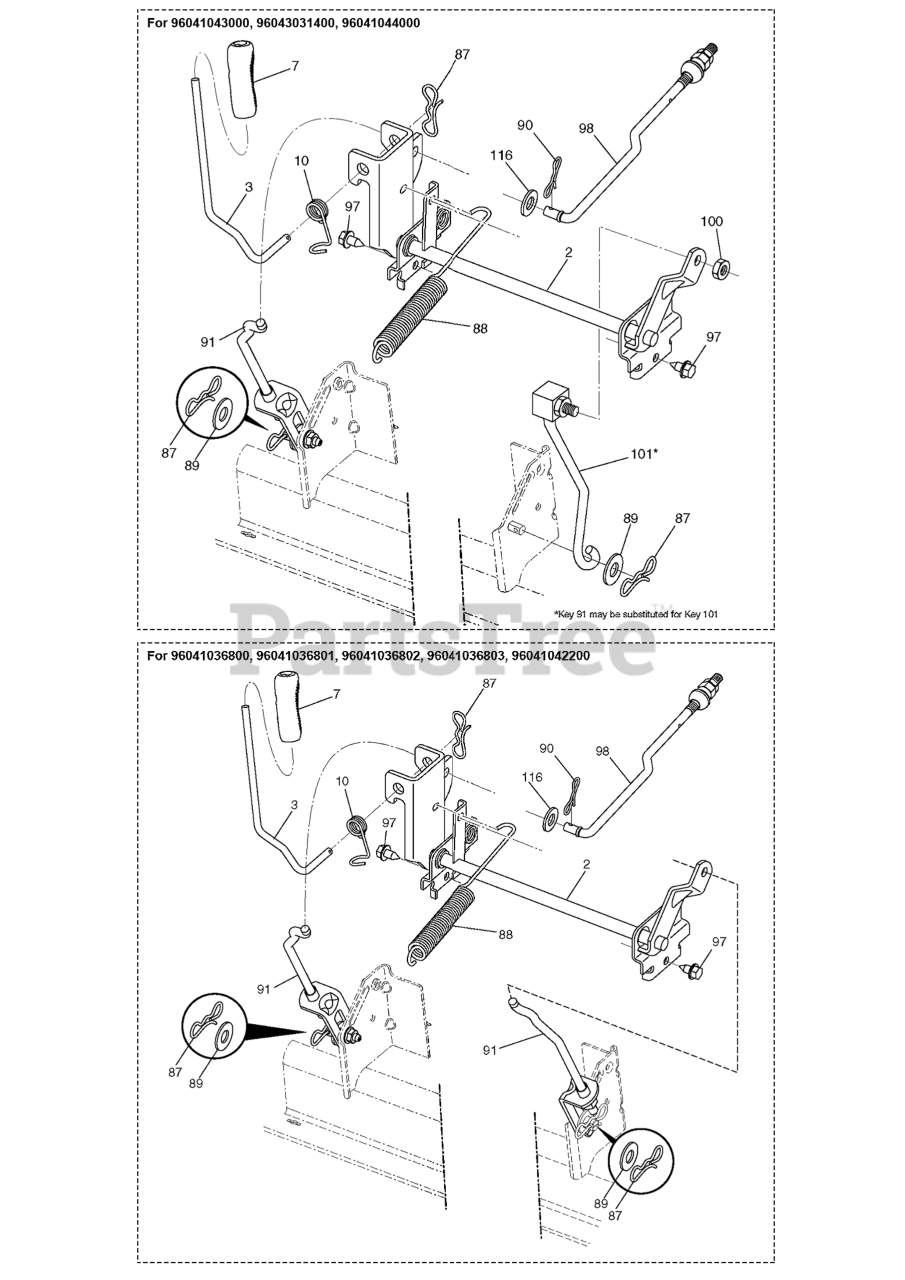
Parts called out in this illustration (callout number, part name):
2	SHAFT.ASM.CROSS.LIFT
3	Levers
3	LEVER.LIFT.HANDLE.LT
7	GRIP.HANDLE.LIFT.PVC.BLACK
10	SPRING.TORSION.LIFT.HANDLE
87	PIN.COTTER.7/16.BOW TI.
88	SPRING.LIFT.ASSIST
89	WASHER.CLEAR.ZINC
90	PIN.COTTER.5/16.BOW TI
91	LINK ASSY LIFT.REAR 10.278
91	Links
97	SCREW, 3/8-16X3/4
98	LINK.ASM.SUSP.FRONT.MW
98	Links
100	Nuts
101	LINK.ASM.LIFT.FIXE.38/42/46"
116	Washers
116	WASHER
